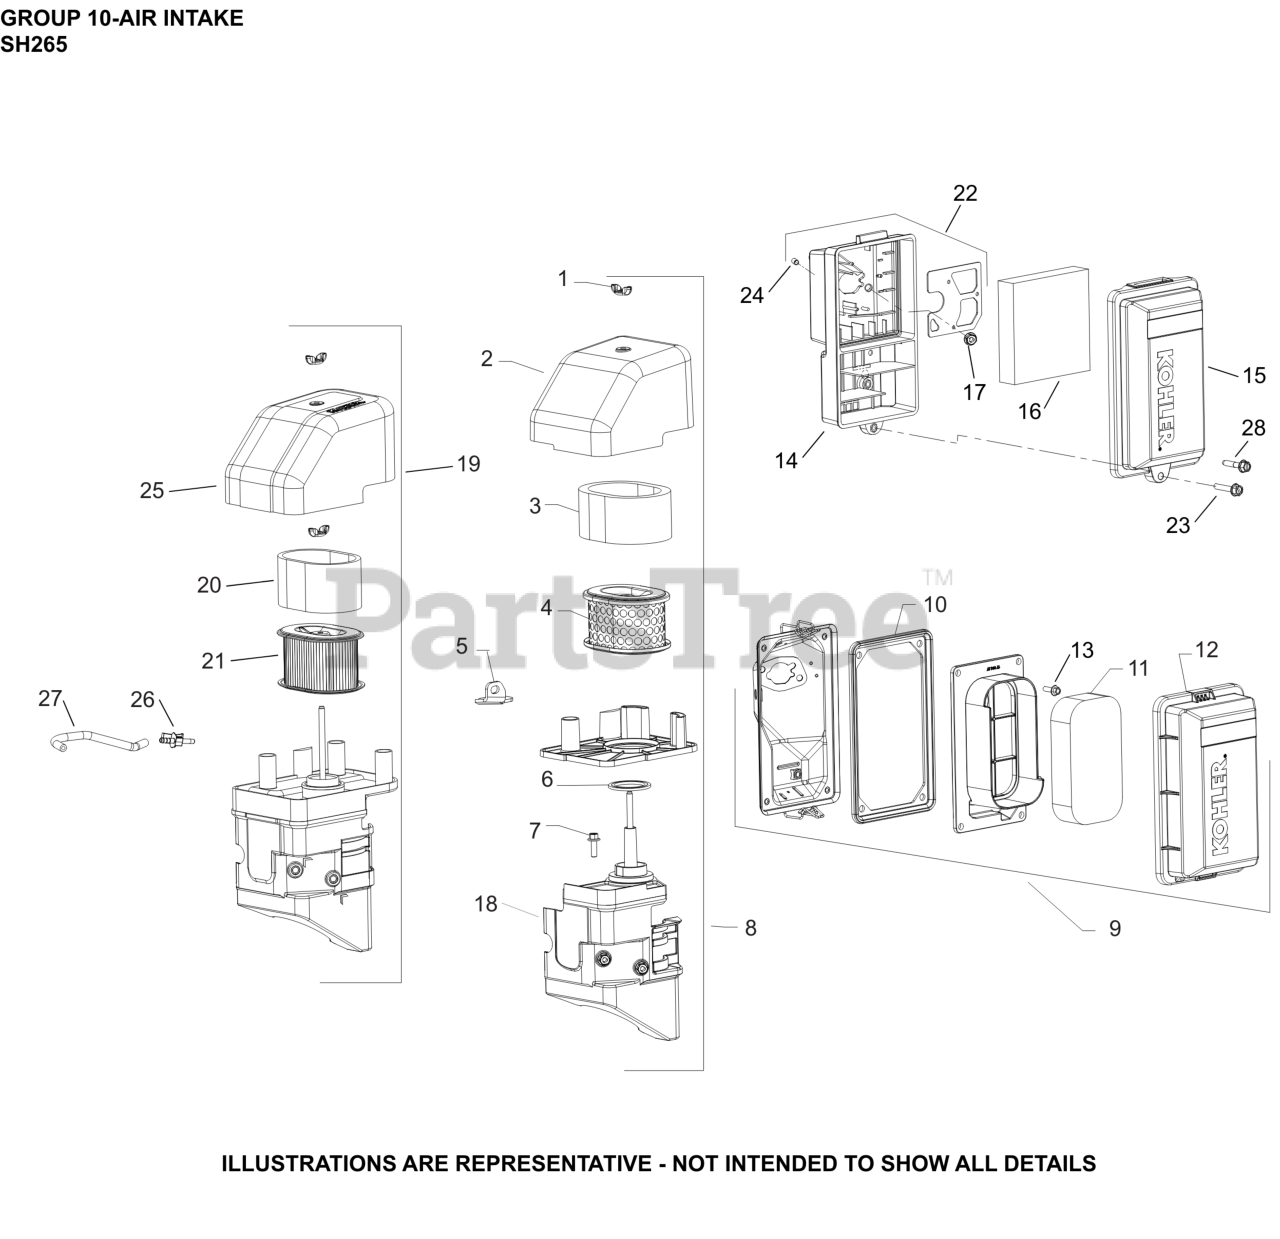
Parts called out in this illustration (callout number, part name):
1	NUT, WING
3	PRECLEANER
4	FILTER, AIR
6	GASKET, AIR FILTER
8	AIR CLEANER ASSEMBLY
17	NUT, HEX FLANGE LOCK (M6)
